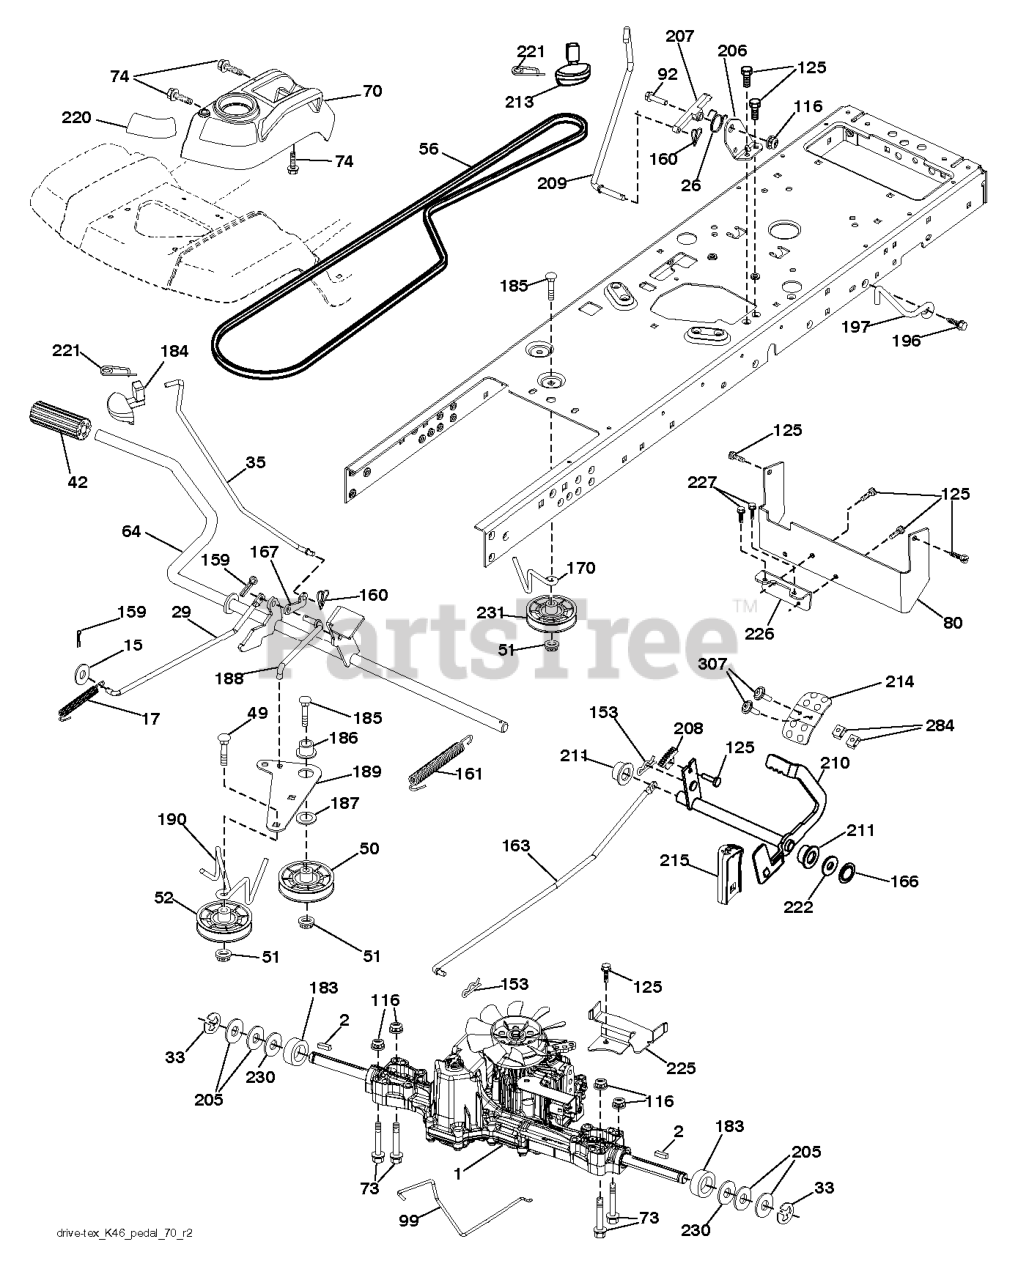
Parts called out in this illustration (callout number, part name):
2	SQUARE KEY
15	WASHER
17	SPRING.BRAKE.K46.GREEN
26	SPRING.RETURN.CRUISE
29	ROD.BRAKE.K46
35	ROD .BRAKE. PARKING. GT. HUSQ.
42	PEDAL COVER T
50	IDLER.FLAT.910.OFFSET
51	NUT LOCK FLG 3/8-16 UNC
52	IDLER.V-GROOVE.910.OFFSET
56	V-BELT.MOWER.92.40.42/K46
64	SHAFT.ASM.PEDAL.BRK.CNTR
70	RP CONSOLE.ASM.PCH.W/TB
73	BOLT
74	SCREW.HI-LO.CONSOLE
80	STRAP TORQUE
92	BOLT
99	ROD.SPRING.BYPASS.K46.LT.Z
116	NUT LOCK HEX FLANGE 5/16-18
125	SCREW
153	RETAINER M
159	COTTER PIN
160	RETAINER CLIP
161	SPRING, RETURN LT
163	ROD.CONTROL.K57R.K46
166	NUT.PUSH.625
167	LATCH.BRAKE.SPRING
170	KEEPER.CENTER SPAN.1.688
183	SPACER AXLE
184	HANDLE.PARKG.BRK.HUSQ X667
186	SPACER.RETAINER
187	WASHER 12/32X2X10GA
188	RP.LINK.CLUTCH.GROUND.DRIVE
189	BELLCRANK.GROUND.DRIVE.TEX.
190	KEEPER.BELLCRANK.DRIVE
196	SCREW 3/8-16X1
197	LINK.CLUTCH.ANIT-ROTAT
206	BRKT.MOUNT.LATCH.CRUIS
207	LATCH.CONTROL.CRUISE
208	GEAR.SECTOR.CONTROL.CR
209	ROD.CONTROL.CRUISE.GT.
210	ROCKER.ASM.PEDAL.CONTR
211	BEARING.NYLON
213	KNOB.CONTROL.CRUSIE.HU
214	PEDAL.FORWARD.HUSQVARNA.DEALER
215	PEDAL.REVERSE.TEX.GT.4
220	REFLECTOR.RH.TEX GT
221	RETAINER.SPRING.CLIP.H
222	WASHER 21/32 X 1-1/4 X 10 GA.
225	KEEPER.BELT.TRANSAXLE.K46
226	BRACKET.MOUNT.TORQUE.K46.TLT
227	SCREW.THDROL.5/16-18X3/4.TTY
230	WASHER.HARDENED
231	IDLER.V-GROOVE.1.688.OFFSET
284	NUT.U-CHNL.1/4-20.550DP.350PNL
307	SCREW.MACHINE.CR.1/4-20
